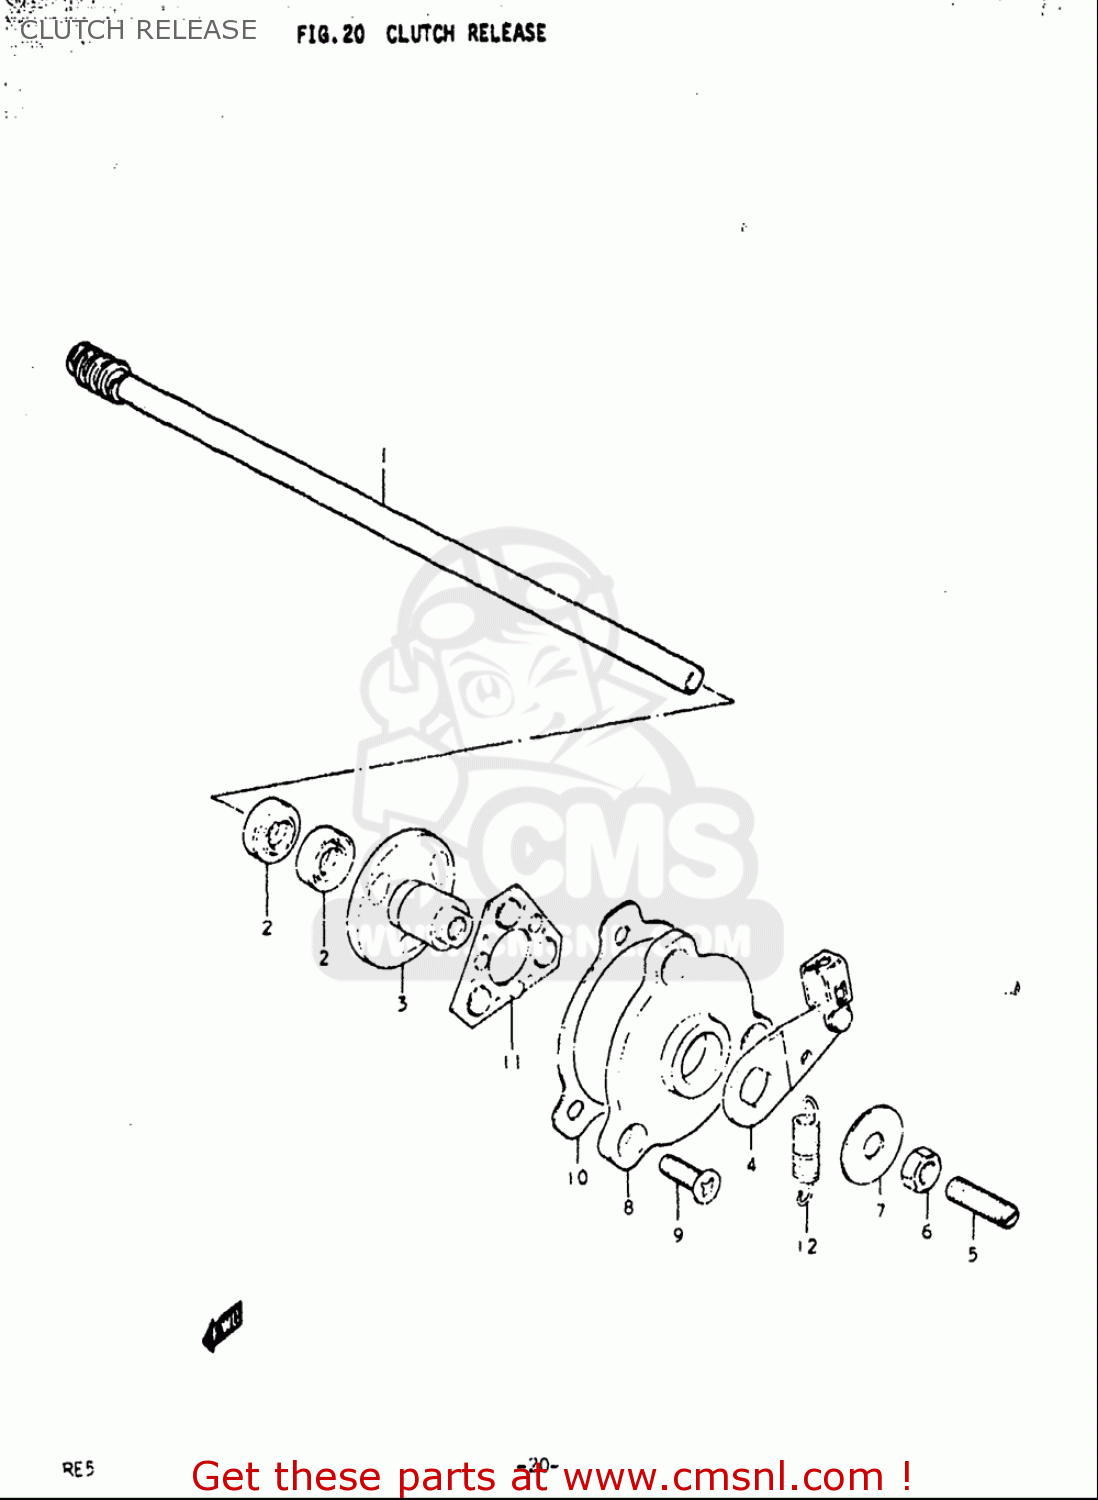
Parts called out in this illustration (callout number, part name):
2	SEAL,OIL(8X20X7)
3	GUIDE,CLUTCH RELEASE,OUTER
5	SCREW
6	NUT
7	WASHER(8.5X26X1.2)
9	SCREW
10	GASKET,BALL GUIDE (NAS)
11	BALL,CLUTCH RELEASE
12	SPRING
